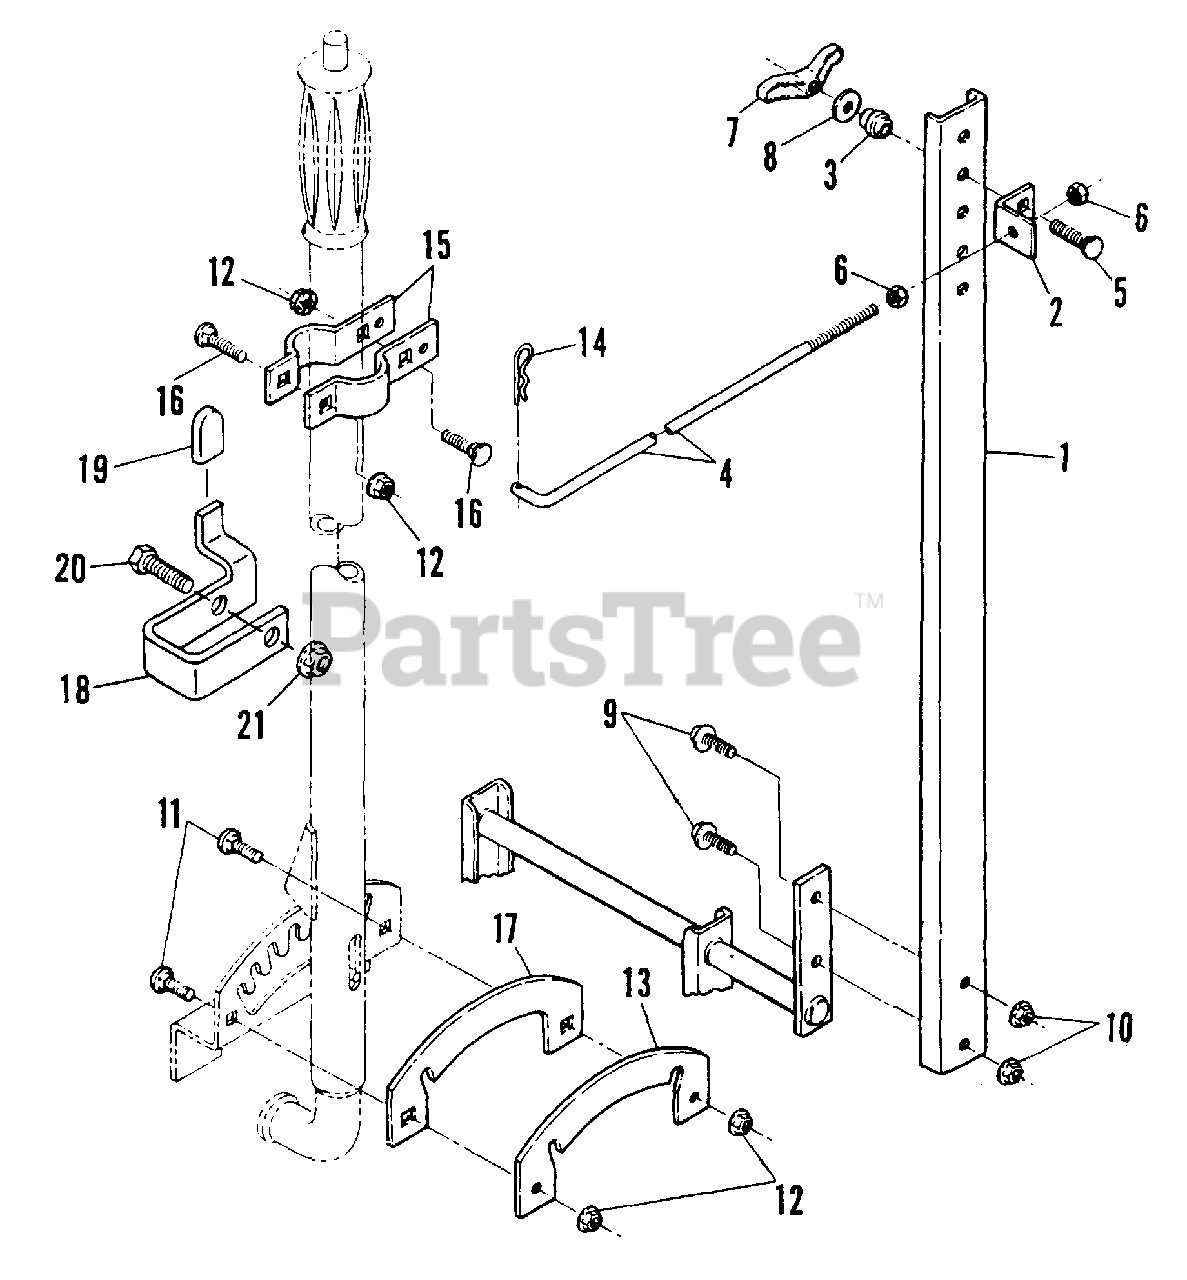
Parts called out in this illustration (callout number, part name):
1	ARM, Lift
2	SWIVEL, Lift Rod
3	SPACER
4	ROD, Lift
5	BOLT, 5/16-18 x 2-1/2" Short Neck Carriage
6	NUT, 3/8-16 Hex
7	NUT, 5/16-18 Wing
8	WASHER, 5/16" x 1-1/4" x 3/32" Flat
9	SCREW, 1/2-13 x 1" Hex Flange Lock
10	NUT, 1/2-13 Hex Flange Lock
11	BOLT, 1/4-20 x 5/8" Flat Head Carriage
12	NUT, 1/4-20 Hex Flange Lock
13	PLATE, Quadrant
14	PIN, 3/32 x 1-1/2" Hair
15	TAB
16	BOLT, 1/4-20 x 1/2" Short Neck Carriage
17	PLATE, Quadrant Float
18	BRACKET, Hood Prop
19	CAP, Vinyl
20	SCREW, 1/4-20 x 1-3/4" Hex Head Cap
21	NUT, 1/4-20 Hex Center Lock
